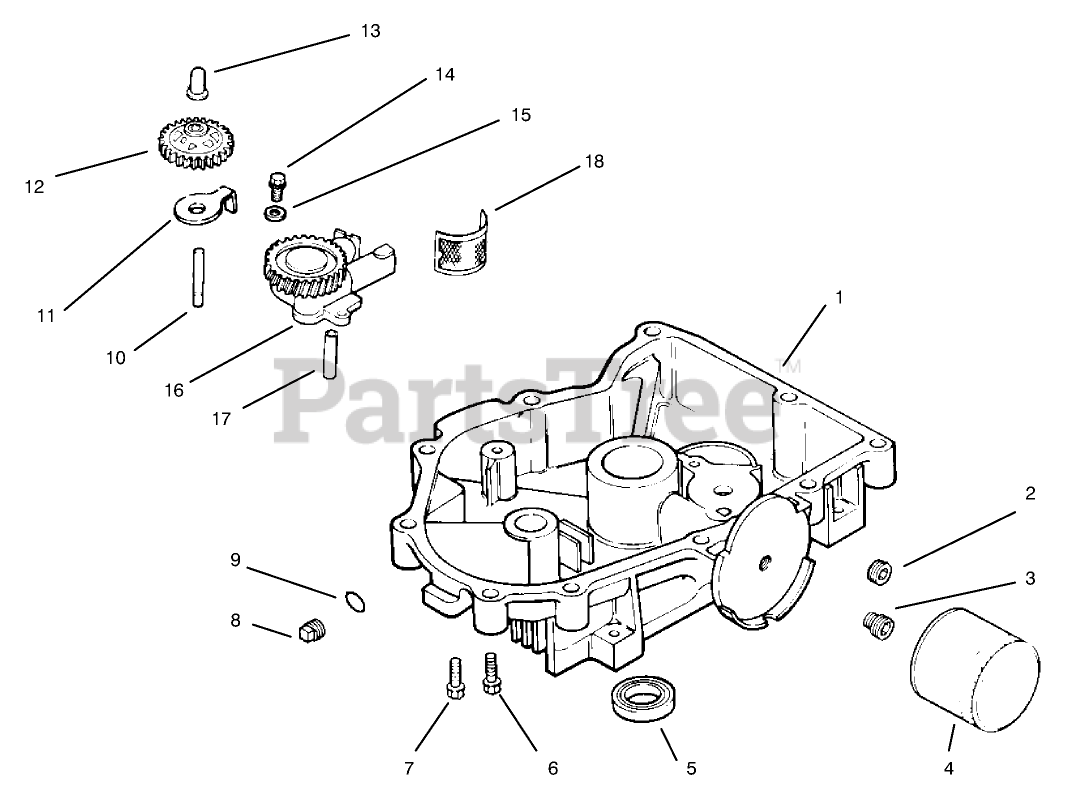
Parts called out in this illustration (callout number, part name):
1	Pan-Oil
2	Plug-Hex
3	Nipple-Filter, Oil
4	Filter-Oil
5	Seal-Oil
6	Screw
7	Screw
8	Plug
9	O Ring
10	Shaft-Gear, Governor
11	Tab-Locking
12	Governor Gear ASM
13	Pin-Governor
14	Screw
15	Washer
16	Oil Pump ASM INC 16
17	Tube-Oil Pickup
18	Screen-Oil
